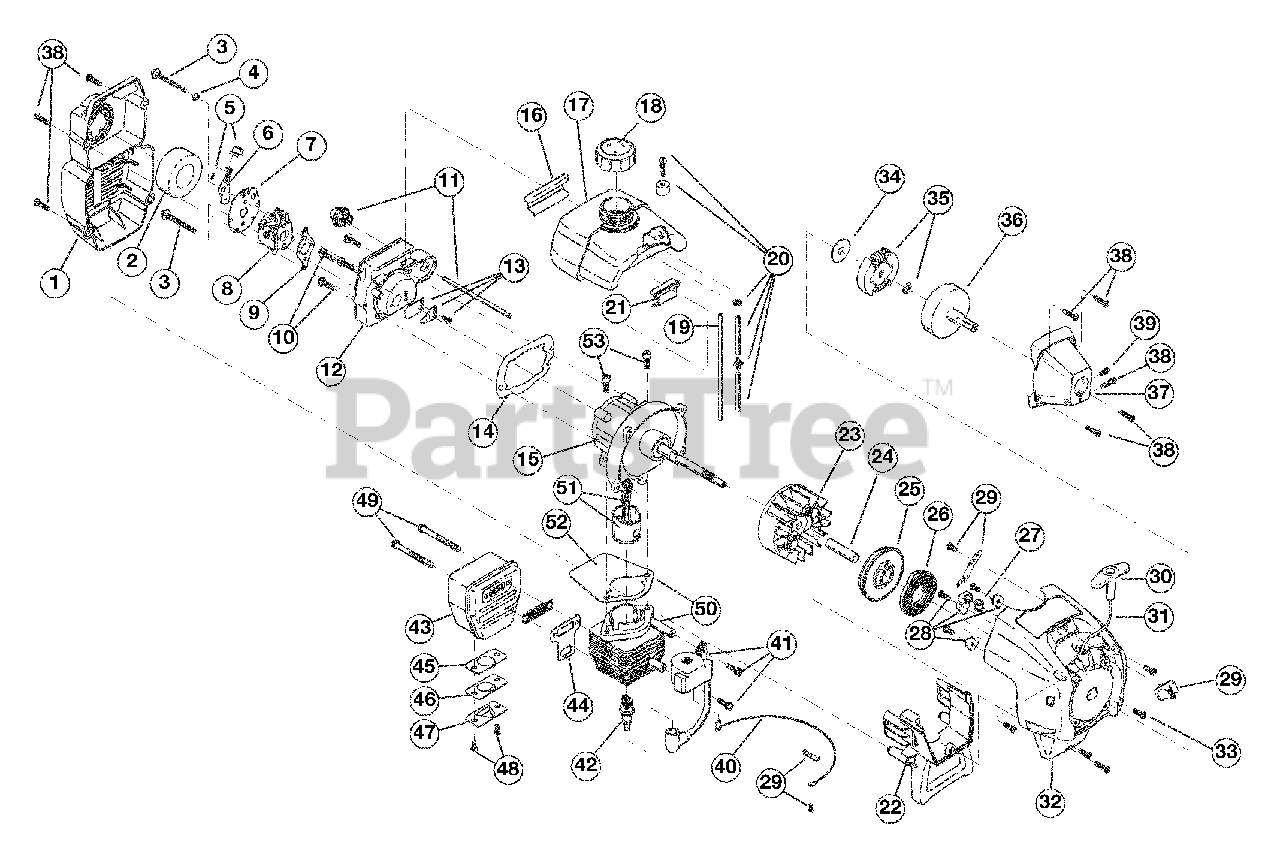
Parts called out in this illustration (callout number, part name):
1	Air Cleaner Assembly
2	Air Cleaner Filter
3	Carburetor Mounting Screw
4	Wavey Washer
5	Choke Knob and Screw
6	Choke Lever Assembly
7	Choke Plate Assembly
8	Carburetor Assembly
9	Carburetor Gasket
10	Carb Mount Screw
11	Primer and Hose Assembly
12	Carb Mount Assembly
13	Reed Assembly
14	Carburetor Mount Gasket
15	Crank Case Service Assembly
16	Rear Mounting Pad
17	Fuel Tank Assembly
18	Fuel Cap
19	Fuel Return Line
20	Fuel Line Assembly
21	Front Mounting Pad
22	Shroud Extension and Stand
23	Flywheel
25	Recoil Pulley
26	Recoil Spring
27	Rope Guide
28	Pulley Retainer Assembly
29	Switch Assembly
30	Pull Handle
32	Starter Housing Assembly
33	Housing Screw
34	Clutch Washer
35	Clutch Rotor Assembly
36	Clutch Drum
37	Clutch Cover Assembly
39	Anti-Rotation Screw
40	Wire Lead
41	Module Assembly
42	Spark Plug
43	Muffler Assembly
44	Exhaust Gasket
45	Spark Arrestor Screen
46	Exhaust Hood Diverter
47	Exhaust Hood
48	Screws
49	Muffler Mounting Bolt Assembly
50	Cylinder Assembly
51	Piston and Rod Assembly
52	Cylinder Gasket
53	Cylinder Bolt
